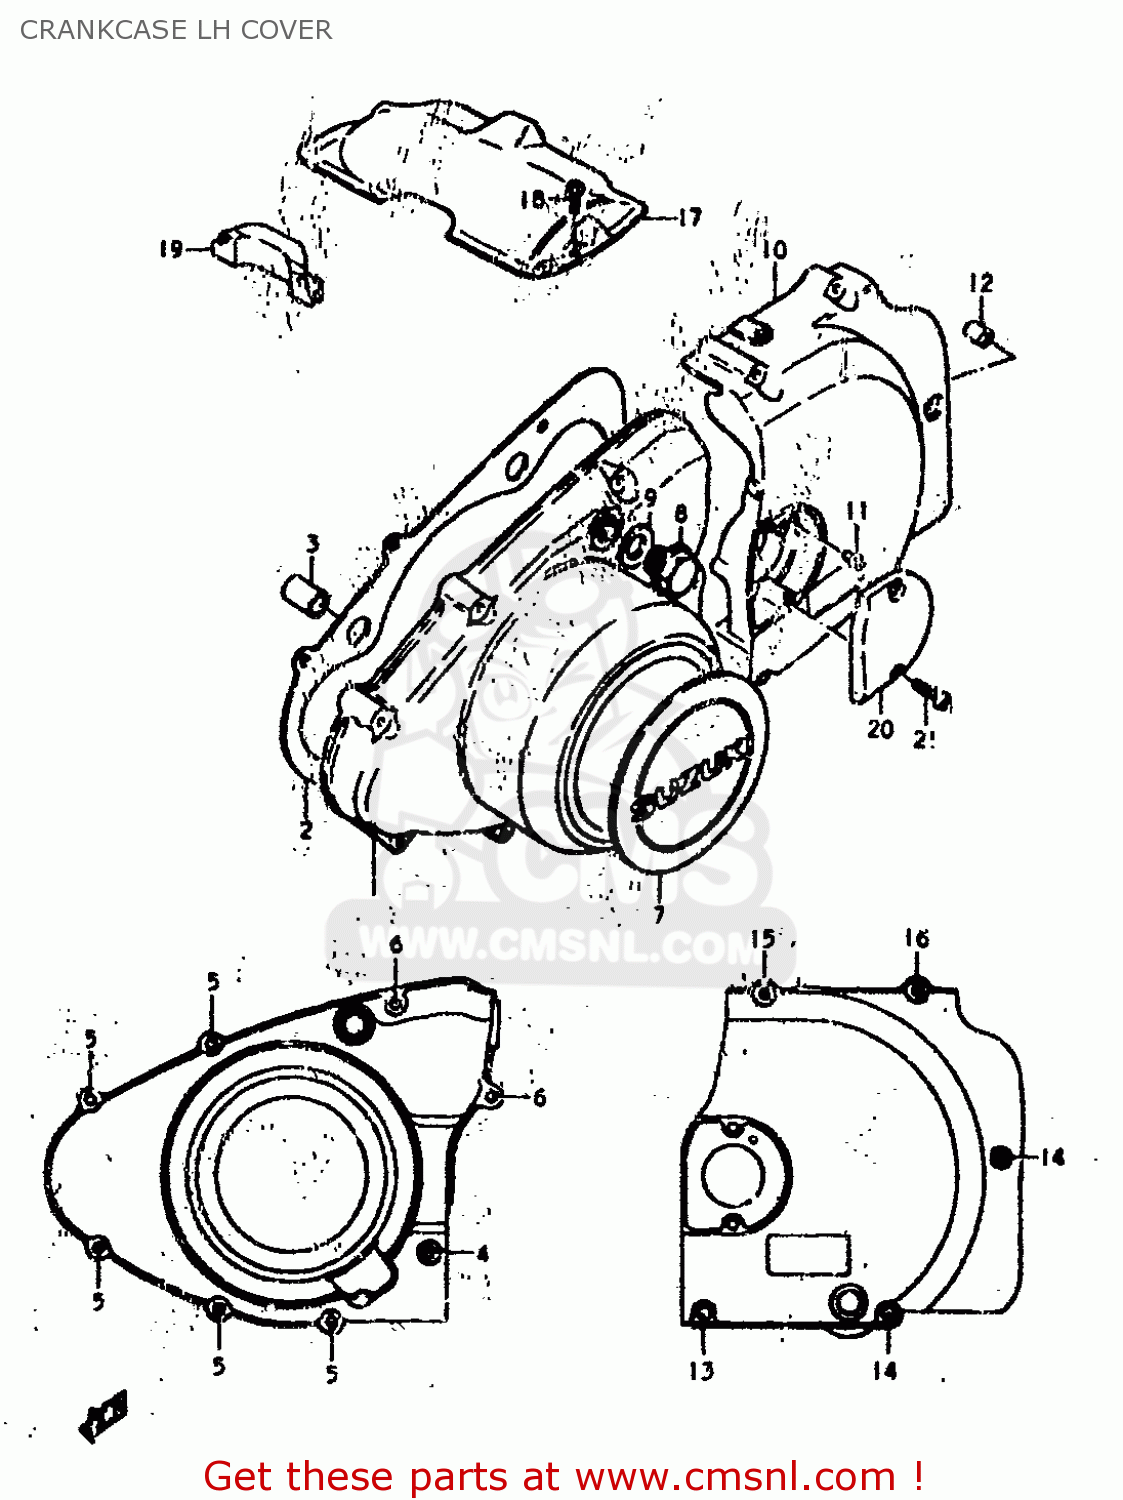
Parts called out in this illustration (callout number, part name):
1	COVER
2	GASKET,MAGNETO COVER (MCA)
3	PIN
4	SCREW
5	SCREW (6X35)
6	SCREW
7	EMBLEM
8	PLUG (14X12)
9	GASKET(14X19.2X2) (NAS)
10	COVER,ENGINE SPROCKET
11	NIPPLE
12	PIN
13	SCREW 6X65
14	SCREW 6X60
15	SCREW
16	SCREW
17	COVER,STARTER MOTOR
18	SCREW
19	GROMMET,STARTING MOTOR
20	CAP,CLUTCH RELEASE ADJUST
21	SCREW
